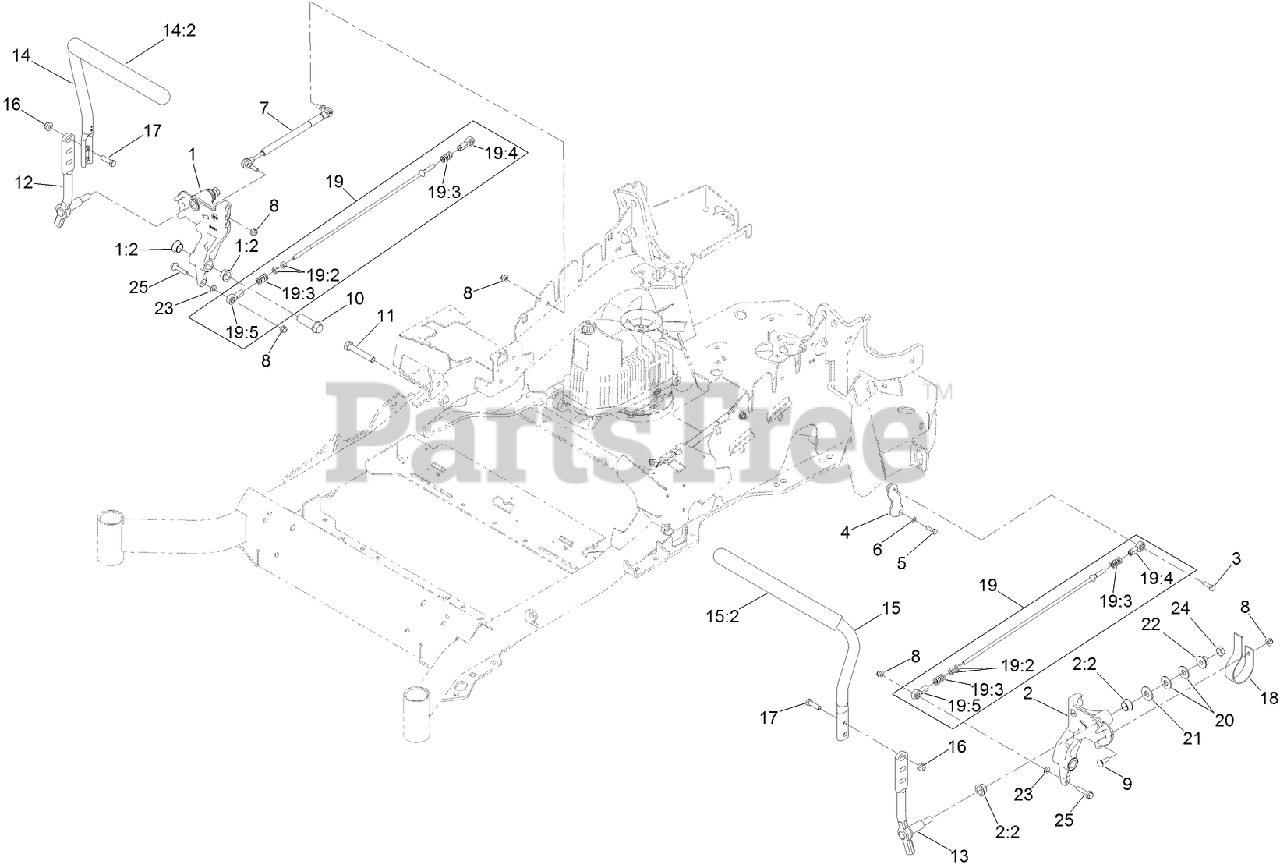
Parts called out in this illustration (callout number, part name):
1	RH MOTION CONTROL AND BUSHING ASM
1:2	BUSHING-FLANGE
2	LH MOTION CONTROL AND BUSHING ASM
2:2	BUSHING-FLANGE
3	SCREW-HH, THREAD LOCKING
4	ARM-CONTROL, PUMP
5	SCREW-HH
6	WASHER-SPRING
7	DAMPER-CONTROL, MOTION
8	NUT-HF, NI
9	BOLT-CARR
10	HUB-THREADED
11	SCREW-HH
12	LEVER-CONTROL MOTION, RH
13	LEVER-CONTROL MOTION, LH
14	RH STEERING HANDLE ASM
14:2	GRIP-CONTROL, LEVER
15	LH STEERING HANDLE ASM
15:2	GRIP-CONTROL, LEVER
16	NUT-HF, NI
17	SCREW-HH
18	SPRING-LEAF
19	FRONT PUMP LINKAGE ASM
19:2	NUT-HEX
19:3	SPRING-COMPRESSION
19:4	BALLJOINT-LH
19:5	BALLJOINT-RH
20	WASHER-SPRING
21	WASHER-FLAT
22	NUT-HF
23	WASHER-PLAIN
24	NUT-JAM
25	SCREW-HHF
